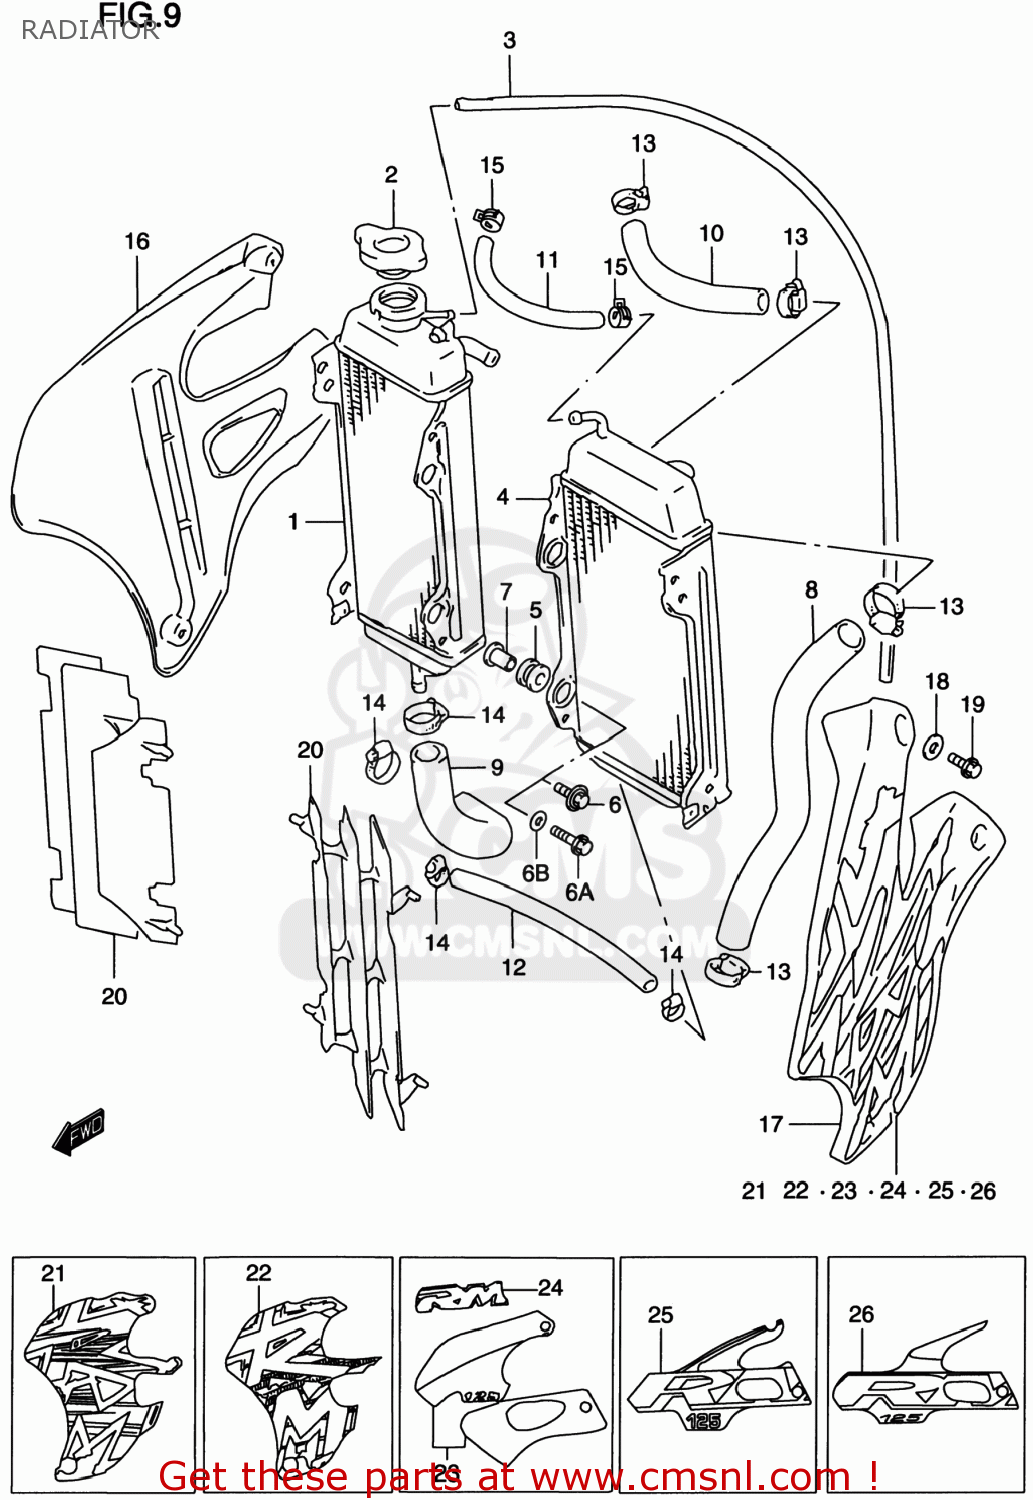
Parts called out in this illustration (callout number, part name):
1	RADIATOR,WATER,R
1-A	NUT
2	CAP,RADIATOR
3	HOSE(5X8X2000)
4	RADIATOR,WATER,L
4-A	NUT
5	CUSHION,RADIATOR LWR
6	BOLT(6X25)
6A	SCREW
6B	WASHER(6.5X24X1.2)
7	SPACER(6.5X10.5X14.1)
8	HOSE,RADIATOR INLET
9	HOSE,RADIATOR OUTLET
10	HOSE,RADIATOR JOINT NO.1
11	HOSE,RADIATOR BYPASS
12	HOSE,RADIATOR JOINT
13	CLAMP
14	CLAMP
15	CLIP
16	COVER,RADIATOR,RIGHT
17	COVER,RADIATOR,LEFT
18	WASHER
19	BOLT
20	LOUVER,RADIATOR
21	EMBLEM,RADIATOR COVER
22	EMBLEM,RADIATOR COVER,R
23	TAPE SET,RADIATOR COVER
24	EMBLEM,RADIATOR COVER,R
25	TAPE,RADIATOR COVER,R
26	TAPE,RADIATOR COVER,R
